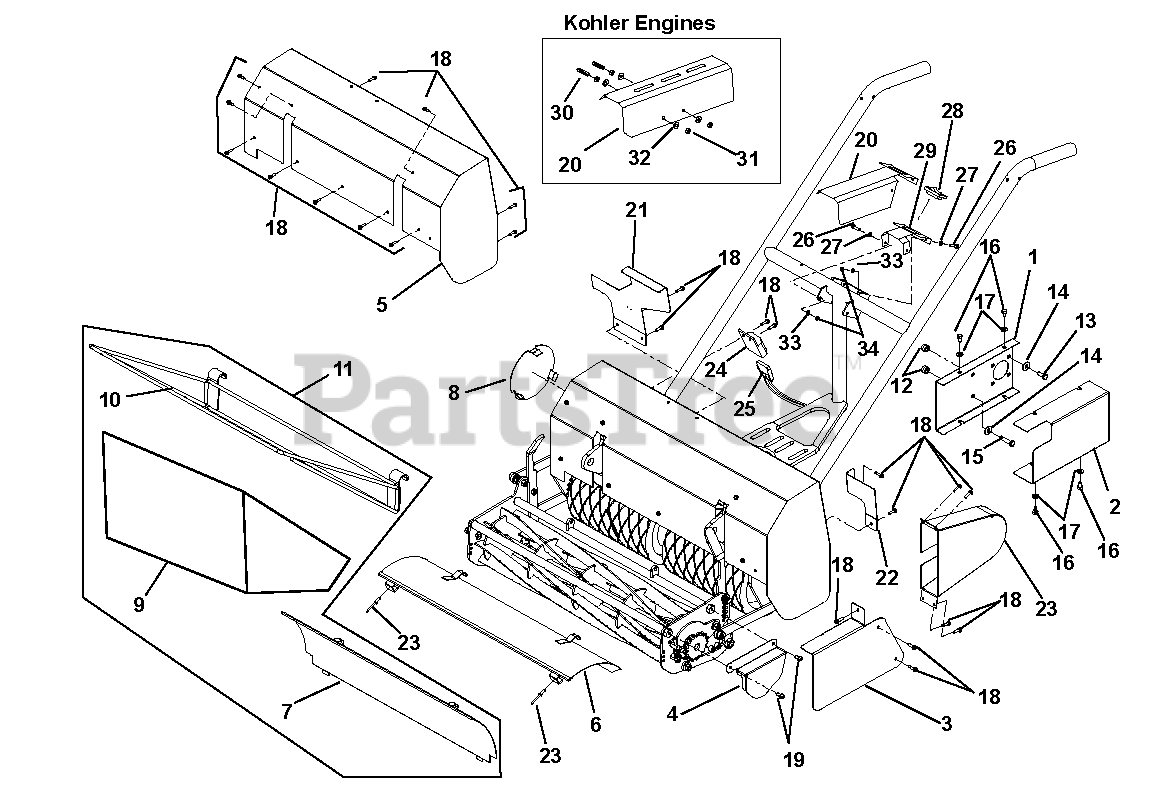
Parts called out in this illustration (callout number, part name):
1	Inner Chain Guard
2	Outer Chain Guard (995313)
3	Chain Guard, Reel
4	Chain Guard, Sprocket
5	Guard, Main 25-Inch (995310)
6	Guard, Reel 25-Inch (995310)
7	Deflector, Front Throw 25-Inch (995310)
8	Cover, Clutch Access
9	Grass Bag, 25-Inch (995310)
10	Frame, Grass Catcher 25-Inch (995310)
11	Kit, Grass Catcher 25-Inch (Includes 7, 9 and 10) (995310)
12	Spacer, Guard (995310, 013)
13	Cap Screw, Hex Head M8 x 1.25 x 20mm
14	Washer, Flat .312
15	Cap Screw, Hex Head M8 x 1.25 x 35mm
16	Cap Screw, Hex Head .25-20 x .50
17	Washer, Flat .25
18	Screw, Hex Self-Drilling 10-16 x .5
19	Screw, Pan Head Slotted, Stainless Steel .25-28
20	Guard, Muffler
21	Shield, Rear Right Hand (995310)
22	Shield, Rear Left Hand (995310)
23	Rivet, Blind Steel .125
24	Module, Interlock Recoil
25	Harness, Wiring
26	Cap Screw, Hex Head .25-20 x .75
27	Washer, Flat .25
28	Switch, Electric Clutch
29	Mount, Switch (995310, 013)
30	Set Screw, Socket Head .25-20 x 1.25 (995310, 013)
31	Nut, Hex .25-28 (995310, 013)
32	Washer, Flat, SAE Hard .25 (995310, 013)
33	Washer, Lock .25
34	Nut, Hex .25-20
